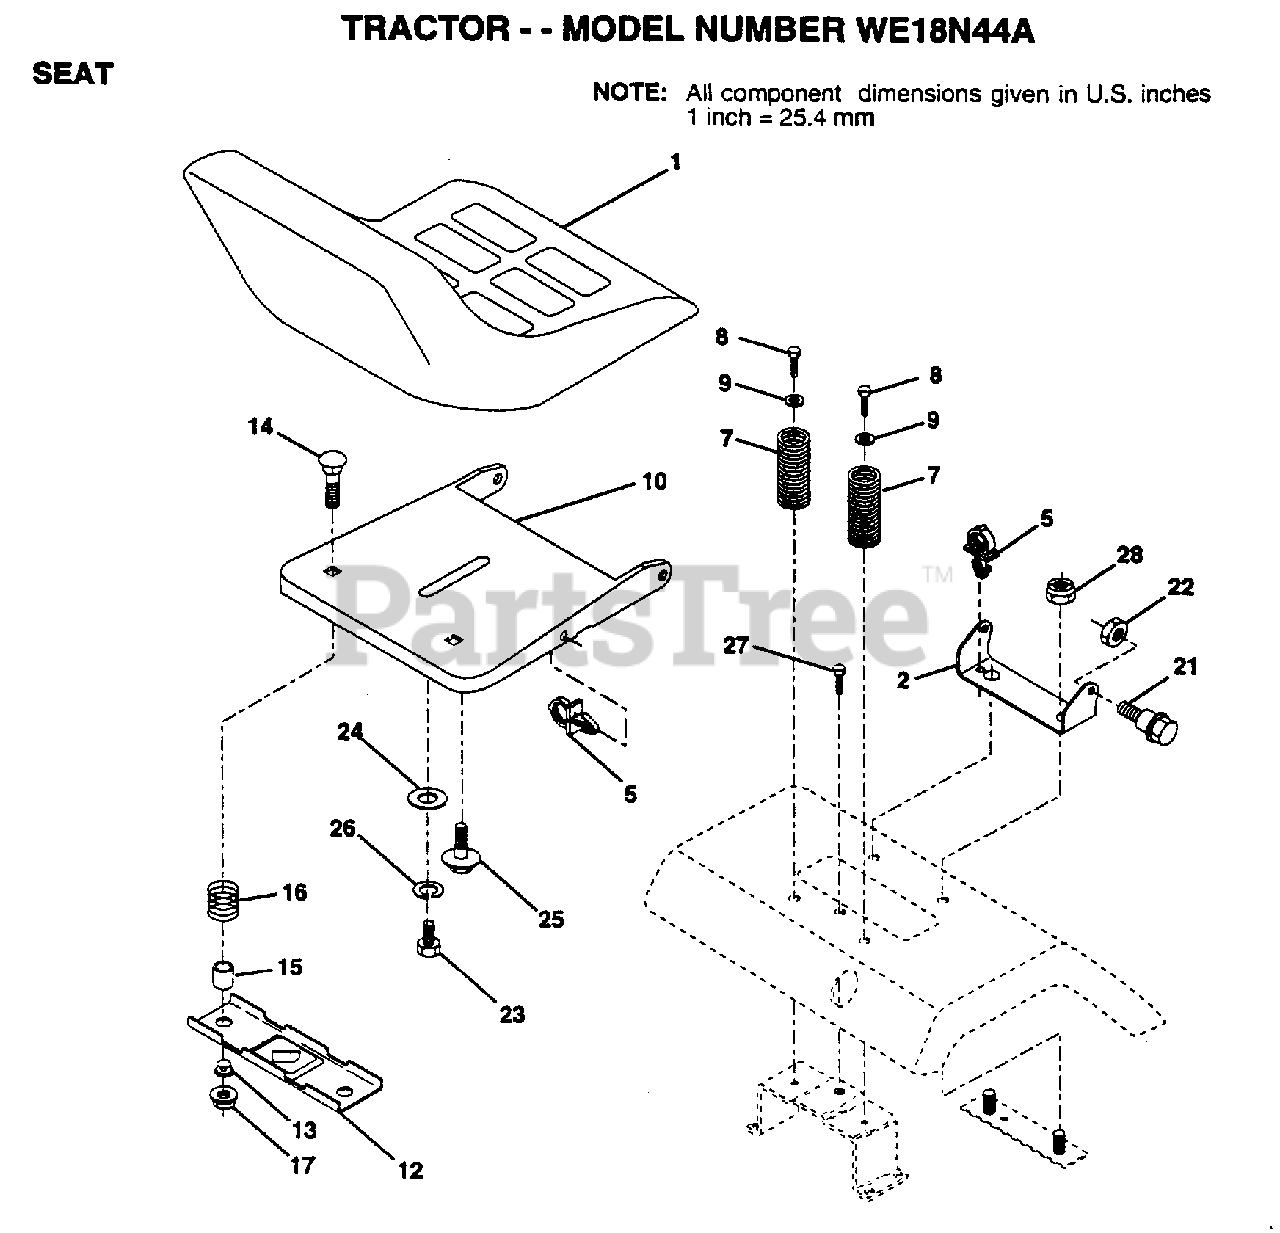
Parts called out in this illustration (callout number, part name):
2	BRACKET PVT SEAT
5	CLIP.PUSH-IN.HING
7	SPRING COMPRESSIO
8	SCREW LT
9	WASHER
12	BRKT SWITCH
13	BUSHING
15	SPACER SPLIT
16	SPRING COMPRESSED
21	BOLT.SHLD.5/16-18
23	BOLT
24	WASHER
25	"BOLT,SHOULDER"
26	LOCKWASHER
27	SCREW LT
